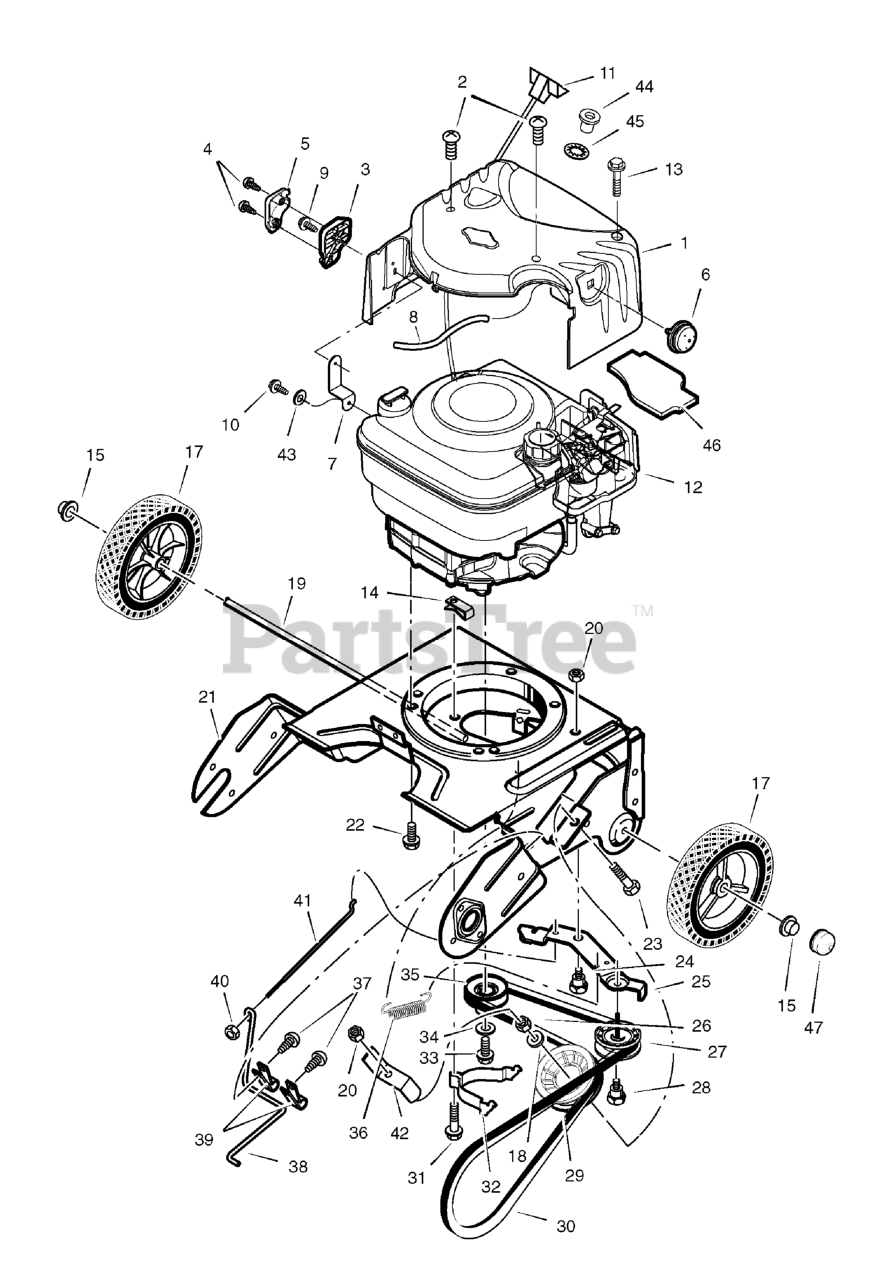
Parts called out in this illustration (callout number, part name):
1	Cover, Top
3	Base, Chute Rod
5	Cover, Chute Rod
6	Primerbulb, Red
7	Bracket, Engine Chute
11	Handle, Starter
12	Engine
14	Retainer
15	Nut, Push Cap
17	Wheel & Tire
18	WASHER, Flat, 13/32
21	Frame, Motor Box
23	Bolt
24	Bolt, Shoulder
25	Bracket, Idler Arm
26	Idler Arm Nut
27	Pulley, V Belt Idler
28	Bolt, Shoulder
29	Pulley, Flat Idler
32	Guide, Belt
33	Screw
34	Washer
38	Arm, Brake
40	Nut
41	Rod, Adjustment
42	Guide, Belt
43	Lockwasher
44	Guide, Rope
45	Spring Grip Washer
46	Seal, Foam
47	Hub Cap 3/20 Plastic Black
